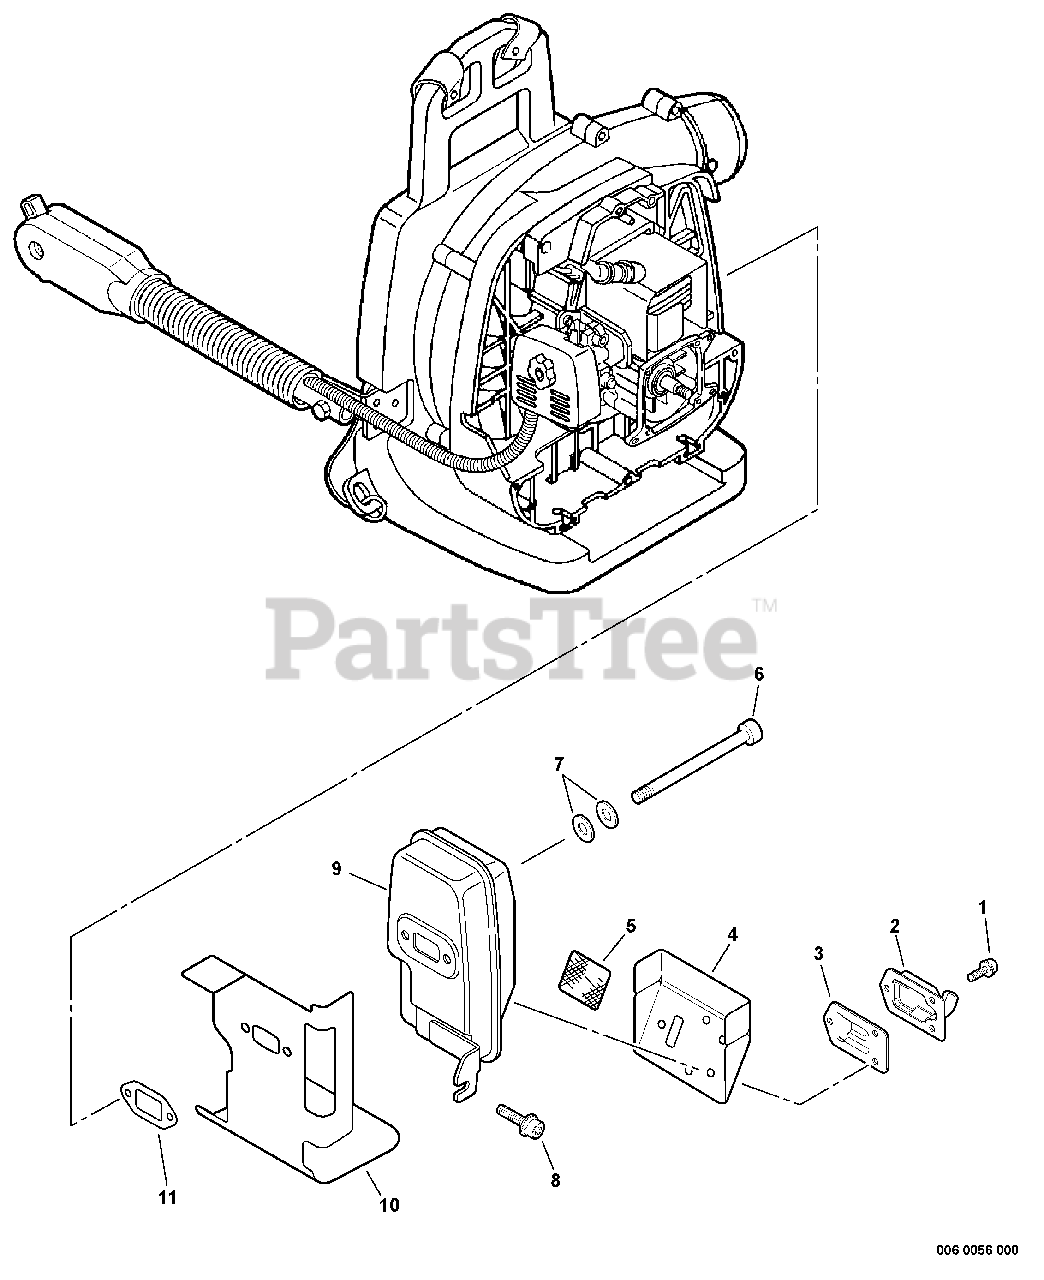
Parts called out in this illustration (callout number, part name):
1	SCREW - 4X10
2	GUIDE, EXHAUST
3	GUIDE, EXHAUST - INNER
4	GASKET, EXHAUST
5	SCREEN, SPARK ARRESTOR
6	SCREW - 5X60
7	WASHER - 5
8	SCREW - 5X16
9	MUFFLER
10	SHIELD, EXHAUST
11	GASKET, EXHAUST
